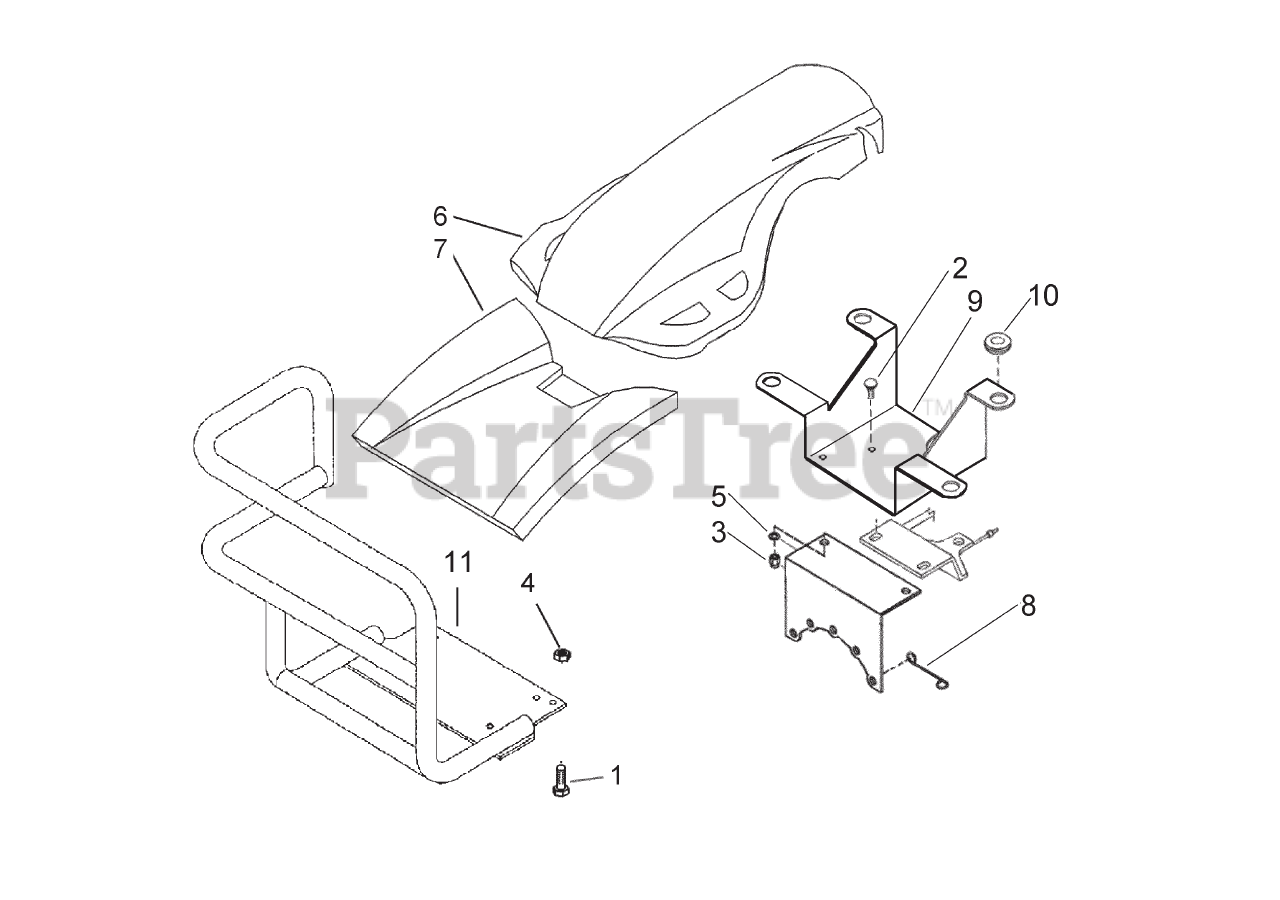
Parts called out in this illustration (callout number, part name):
1	CAP SCREW, M8X40 UNI 5739-8G
2	BOLT, M6 X 16
3	NUT, LOCKNUT, M6
4	NUT, FLANGED, LOCK M8
5	WASHER, FLAT, M6
6	COVER, HANDLEBAR
7	GUARD, LOWER
8	SUPPORT, GAS CABLE SHEATH
9	SHIELD SUPPORT, RECOIL ONLY!!!
11	BUMPER, WRAP AROUND
